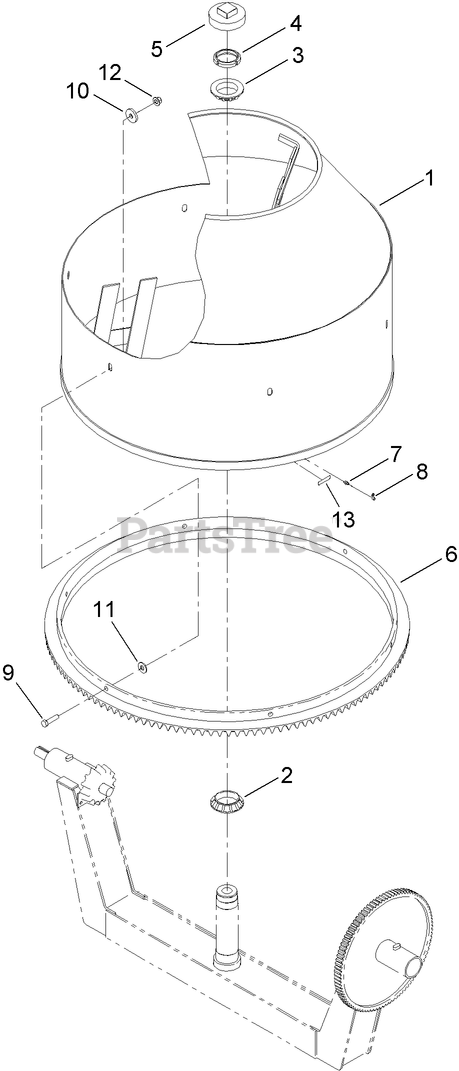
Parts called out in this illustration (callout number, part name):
2	BEARING
3	BEARING
4	NUT-LOCK
5	PLUG-PIPE
6	GEAR-RING
7	FITTING
8	CAP-PLUG
9	SCREW-HH
10	WASHER-FLAT
11	WASHER-FLAT
12	NUT-LOCK
13	DECAL-GREASE
